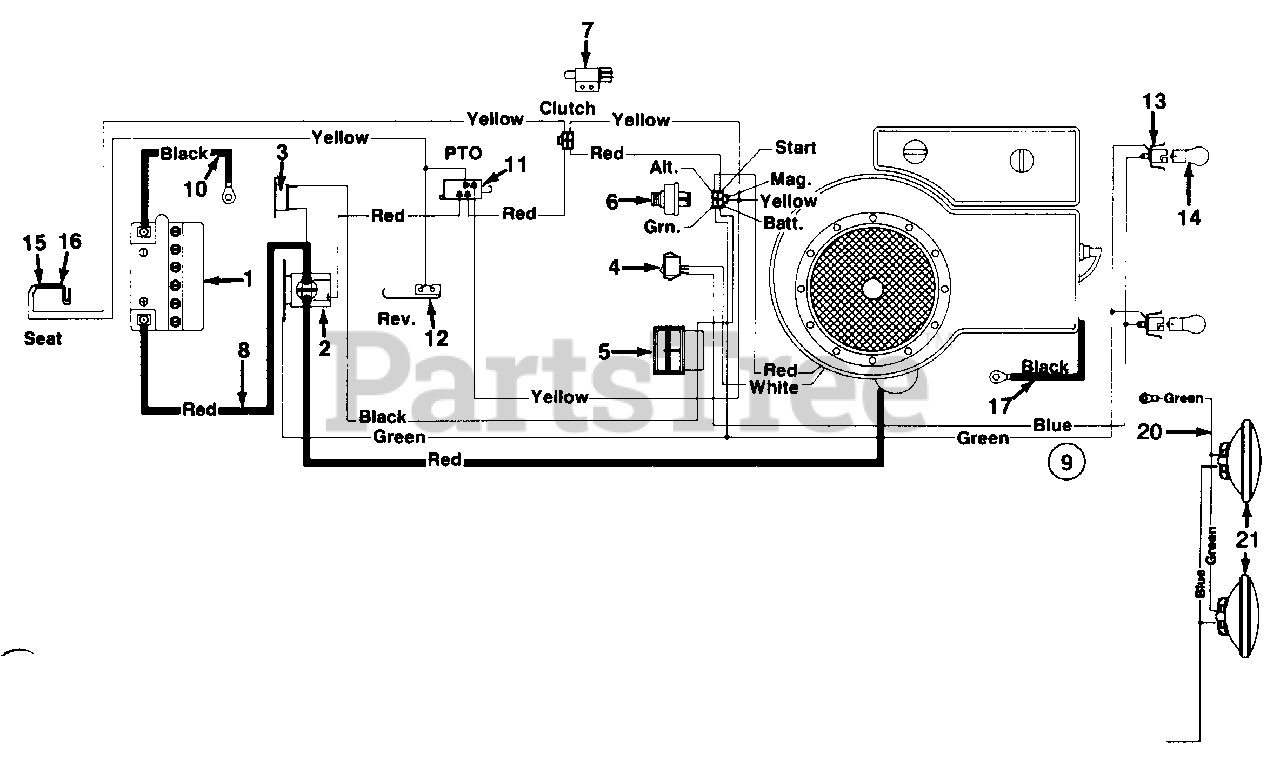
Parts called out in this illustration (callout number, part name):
1	Battery
2	Solenoid
3	Circuit Breaker
4	Light Switch
5	Ammeter
6	Ignition Switch
7	Safety Switch
8	Electric Wire 8" Lg.
9	Wire Harness-B&S w/Taillights
10	Ground Wire 11.5" Lg.
11	Safety Switch
12	Safety Switch
13	Socket
14	Bulb
15	Safety Switch
16	Safety Switch
17	Bulb
20	Ground Wire 7.5" Lg.
21	Round Headlight
